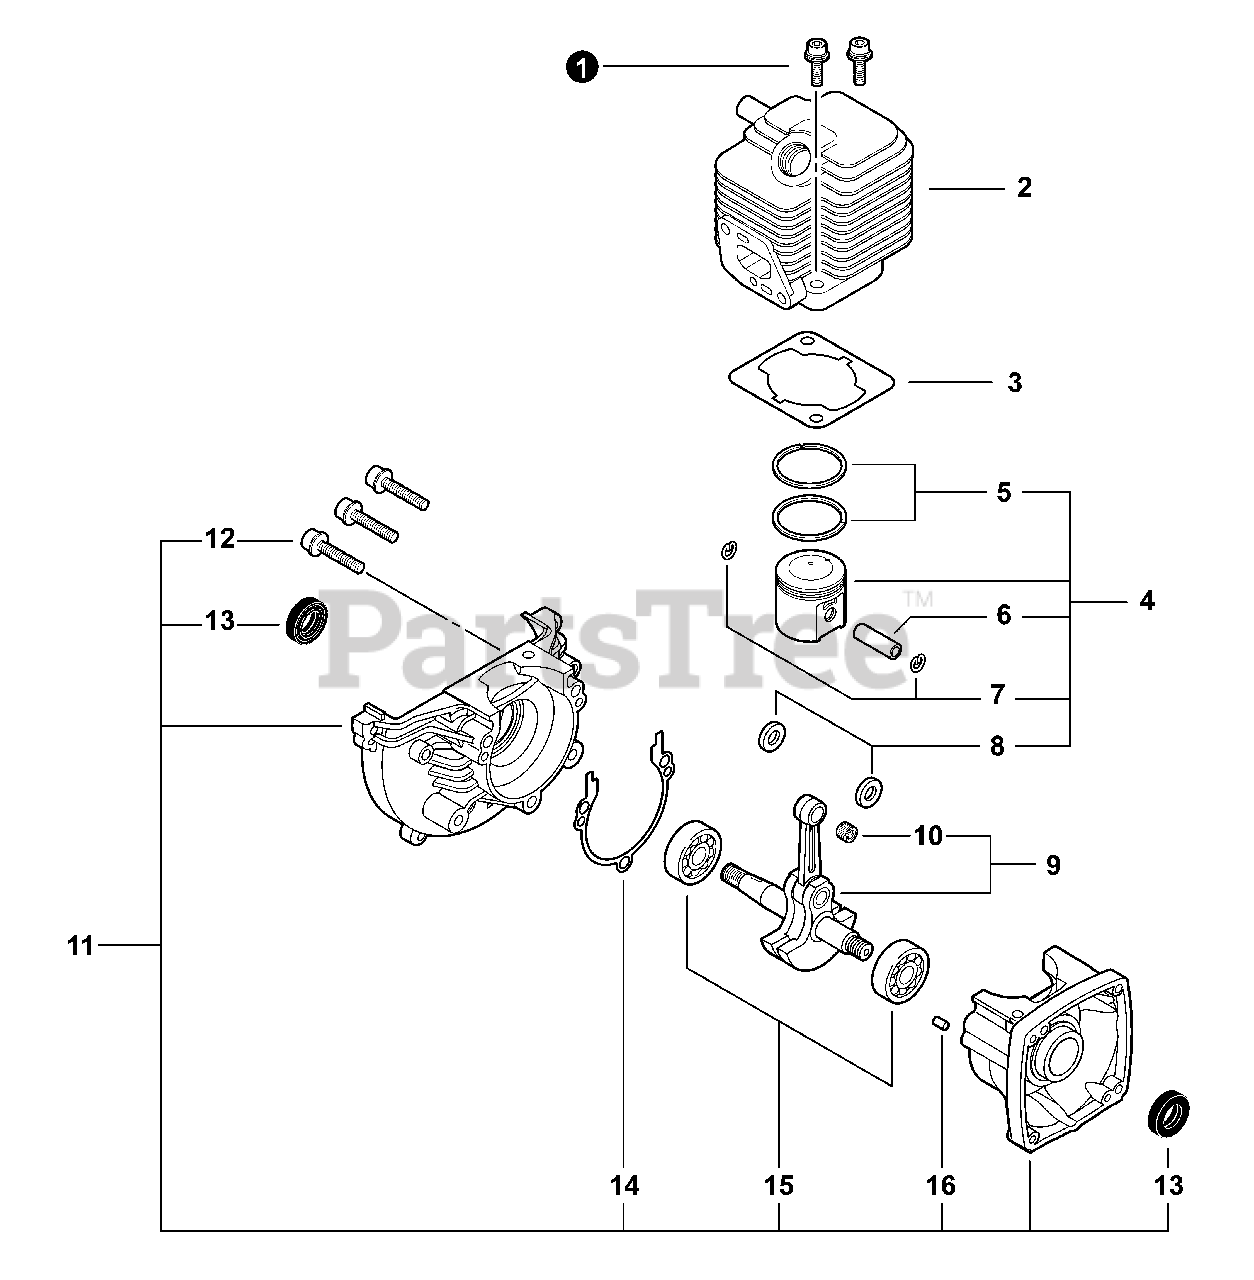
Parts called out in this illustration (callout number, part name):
1	BOLT 5×22
2	CYLINDER
3	GASKET, CYLINDER
4	PISTON KIT
5	RING, PISTON
6	PIN, PISTON 8
7	RING, SNAP
8	WASHER 8.2×13×0.8
9	CRANKSHAFT ASSY
10	BEARING, NEEDLE 8
11	CRANKCASE KIT
12	BOLT 5×28
13	SEAL, OIL 12
14	GASKET, CRANKCASE
15	BEARING, BALL
16	PIN, LOCATING 4×8
